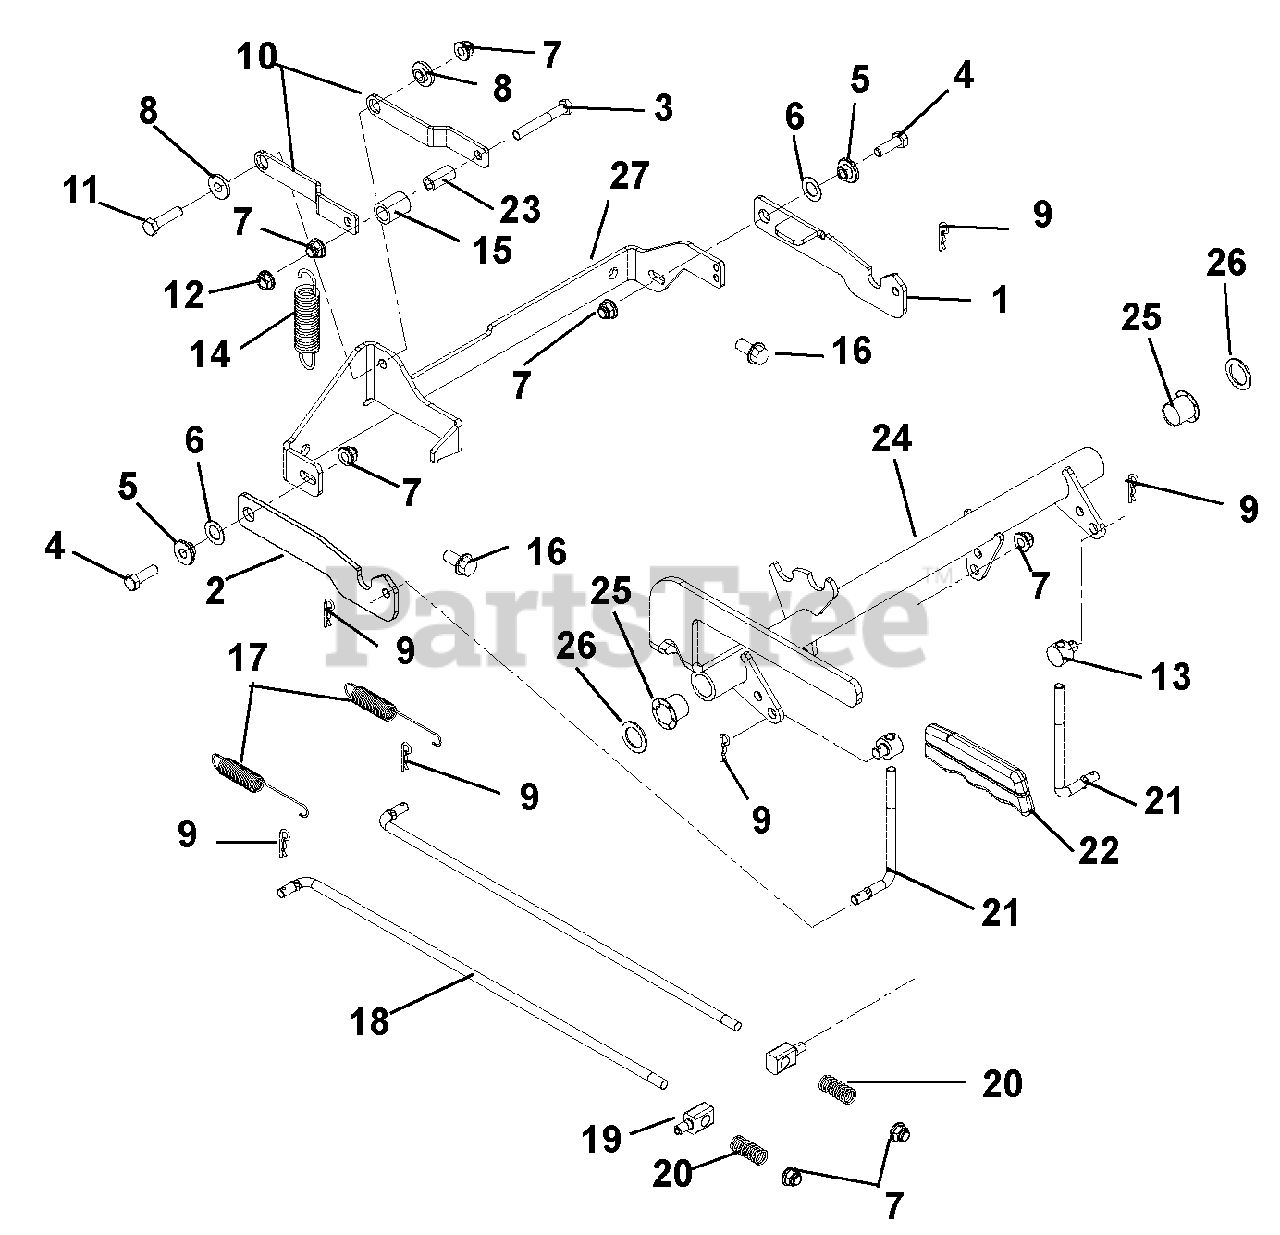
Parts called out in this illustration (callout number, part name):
1	Link, Brake Interlock
2	Interlock, Brake
3	Bolt, Hex .31-18 x 2.25 Grade 5
4	Bolt, Hex .31-18 x 1.00 Grade 5
5	Bushing, Flange .312 x .500 x .344 x .880
6	Washer, Flat Steel .505 x .875 x .024
7	Nut, Flange Nyloc 5/16-18
8	Shoulder Spacer
9	Pin, Hair Internal .08 x .18 x 1.18
10	Arm, Brake Cam
11	Bolt, Hex .31-18 x 1.25 Grade 5
12	Nut, Locking Top Flange .31-18
13	Trunnion, Brake
14	Spring, Tension .105 x .812 x 3.88
15	Roller, Cam Lock
16	Screw, Tapping .38-16 x .75 Hex Washer Head
17	Spring, Tension .056 x .60 x 4.40
18	Rod, Park Brake
19	Pin, Pivot
20	Spring, Compression
21	Link, Interlock Brake
22	Grip, Park Brake
24	Weldment, Brake Shaft
25	Bushing, IGLIDE Clip
26	Washer, Flat Steel .754 x 1.125 x .062
27	Bracket, Brake Mounting
